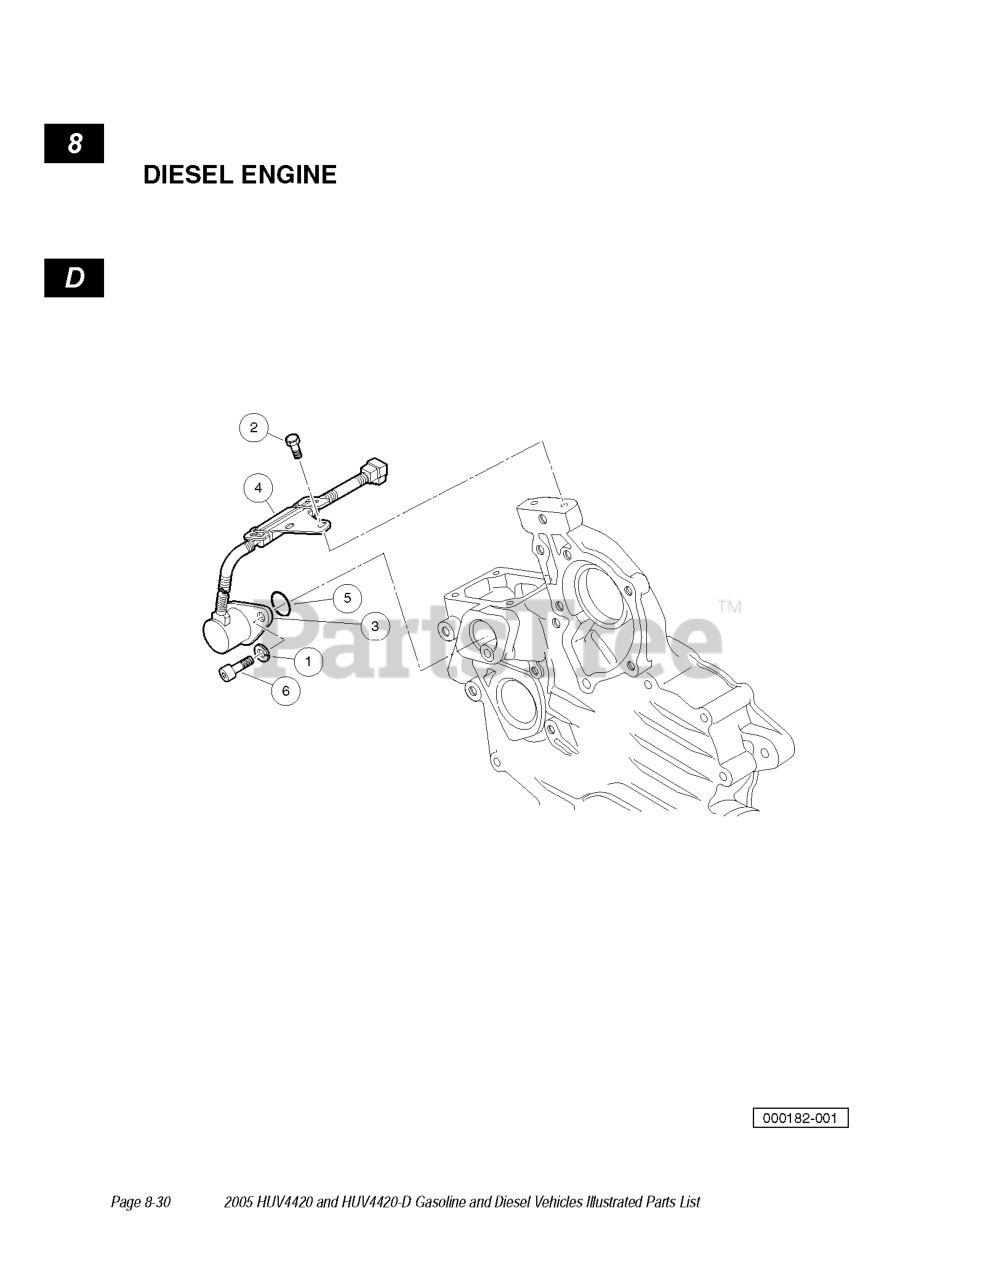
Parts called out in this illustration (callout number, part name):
2	BOLT, SOLENOID, STOP, D722
3	SOLENOID-STOP
4	STAY-SOLENOID
5	BALL-CHECK-D722CB
6	BOLT-SOLENOID-STOP
